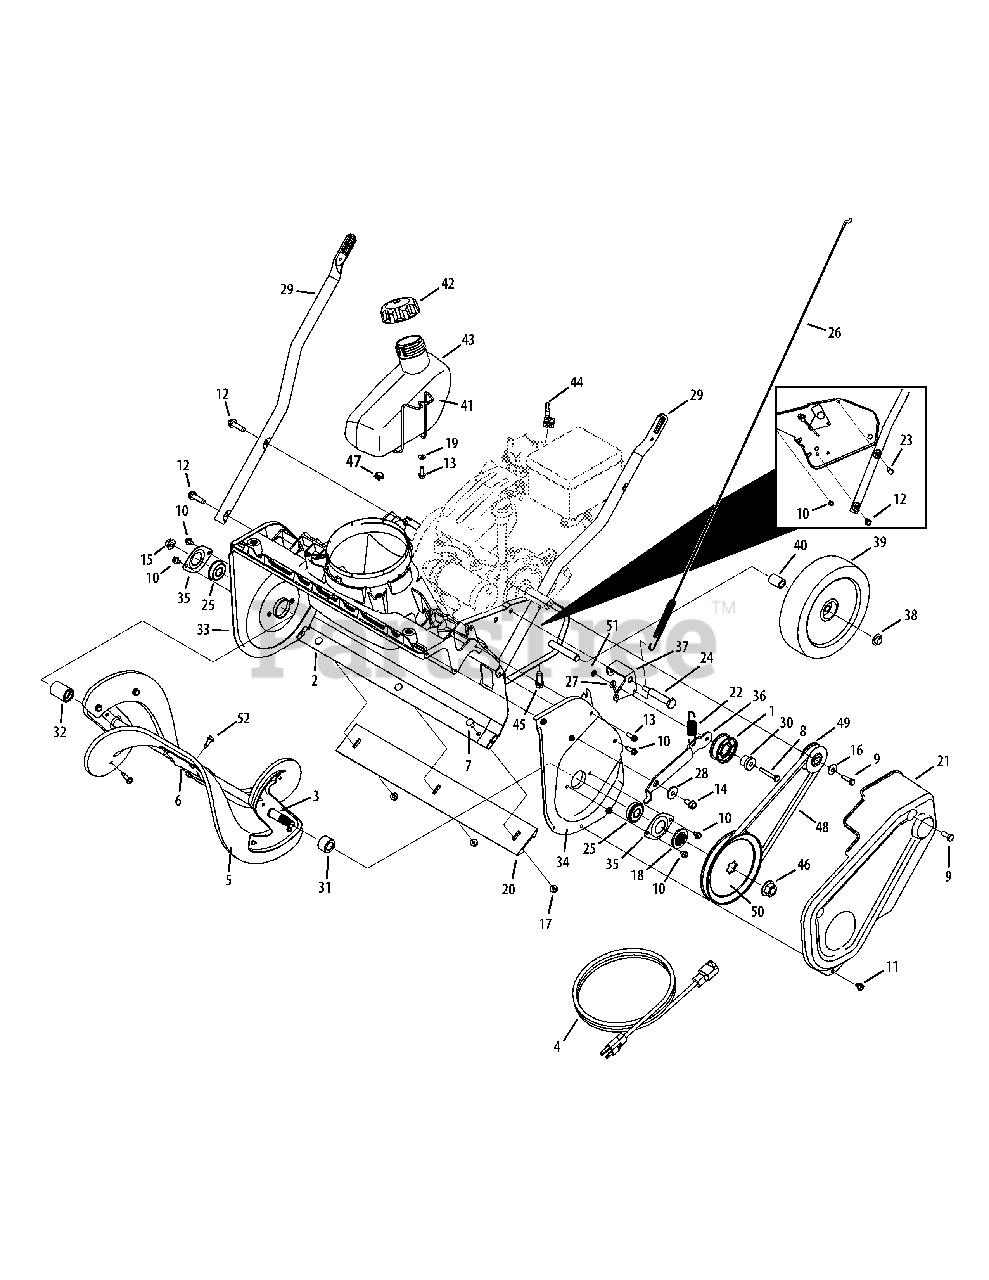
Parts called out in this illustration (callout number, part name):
1	Idler Pulley Ass’y
2	Frame Assembly - Orange
4	3-Prong Extension Cord
5	Rubber Auger Paddle Kit
6	Center Auger Bracket
7	Carriage Bolt 1/4-20 x .62
8	Hex. Washer Screw 1/4-20 x 1.5
9	Hex L-Bolt 5/16-24 x .75 Gr. 5
10	Hex. Washer Screw 1/4-20 x .625
11	Hex Wash S-Tapp Scr 1/4-20 x .50
12	Hex. Washer Screw 5/16-18 x 1.25
13	Hex. Washer Screw 1/4-15 x .75" Lg.
14	Screw, 5/16-18 x .75
15	Hex L-Flanged Nut 3/8-16 Gr. F Nylon
16	Thrust Washer .343 x .880 x .062
17	Flange Locknut 1/4-20 Gr. F, Nylon
19	Washer .265 x 1.0 x .030
22	Extension Spring ..70 x 3.035
23	Hex Screw 5/16-24 x 1.25
24	Shoulder Bolt 5/16-24 x .496 x 2.18
25	Ball Bearing .500 x 1.375 x .4375
27	Drive Cable Wire Support
28	Shoulder Spacer .25 Thk.
30	Shoulder Spacer
31	LH Auger Spacer
32	RH Auger Spacer
33	RH Auger Plate - Orange
34	LH Auger Plate - Orange
35	Bearing Cup - Orange
37	Idler Cable Bracket
38	Push Cap, 1/2"
39	Wheel, 7"
40	Spacer, .525 x .775 x .835
41	Gas Tank Wire Support
42	Fuel Cap
43	Fuel Tank
44	Choke Extension Lever
45	Hex Wash HD Tap Scr 3/8-16 x .88
46	Flanged Nut 7/16-20
48	Belt .500 x 35.06
49	Pulley Half .625 x 2.25
51	Push Nut, .25 x .50
52	Hex Wash HD Tap Scr 1/4-20 x .75
